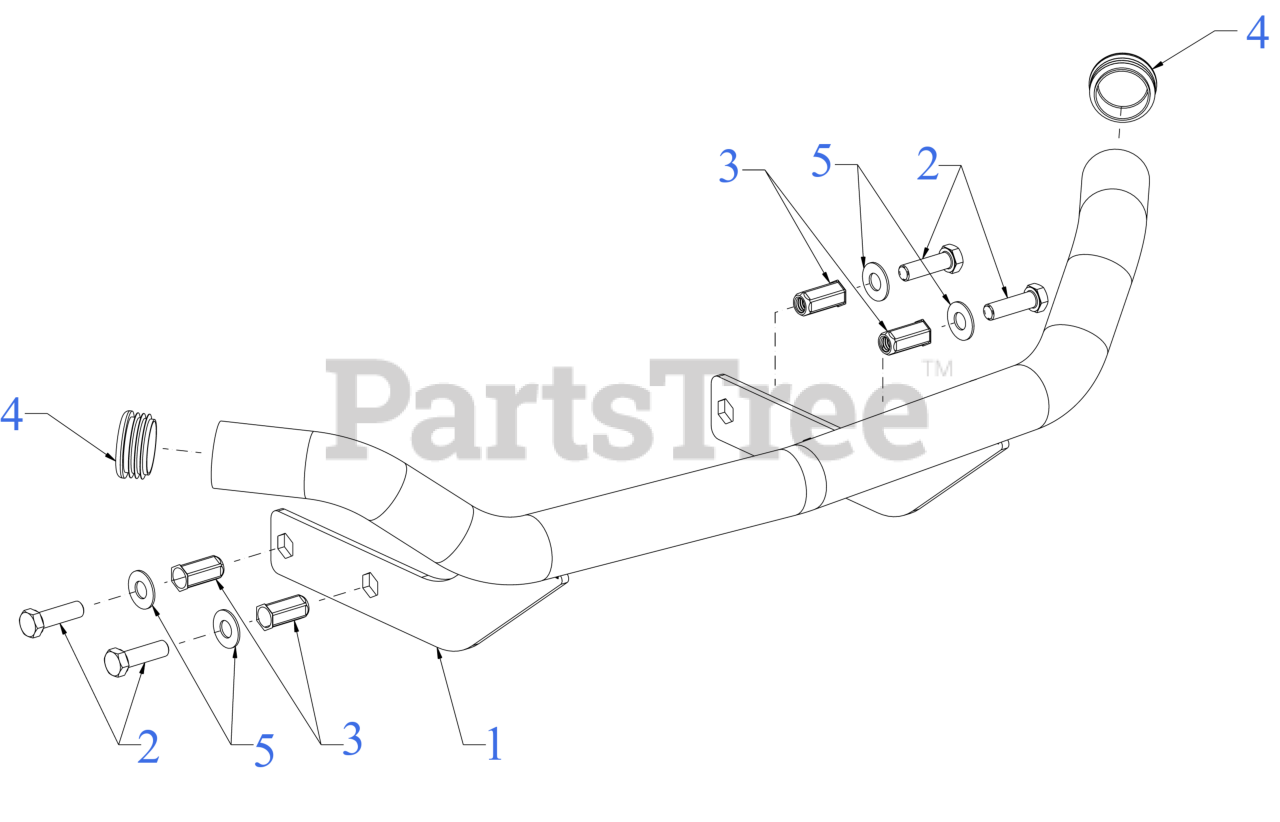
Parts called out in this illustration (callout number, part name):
1	BUMPER (SILVER)
2	SCREW 3/8-16 x 1.25 GR5
3	NUT RIVET 3/8-16
4	BUMPER CAP
5	FLAT WASHER .401X.88
